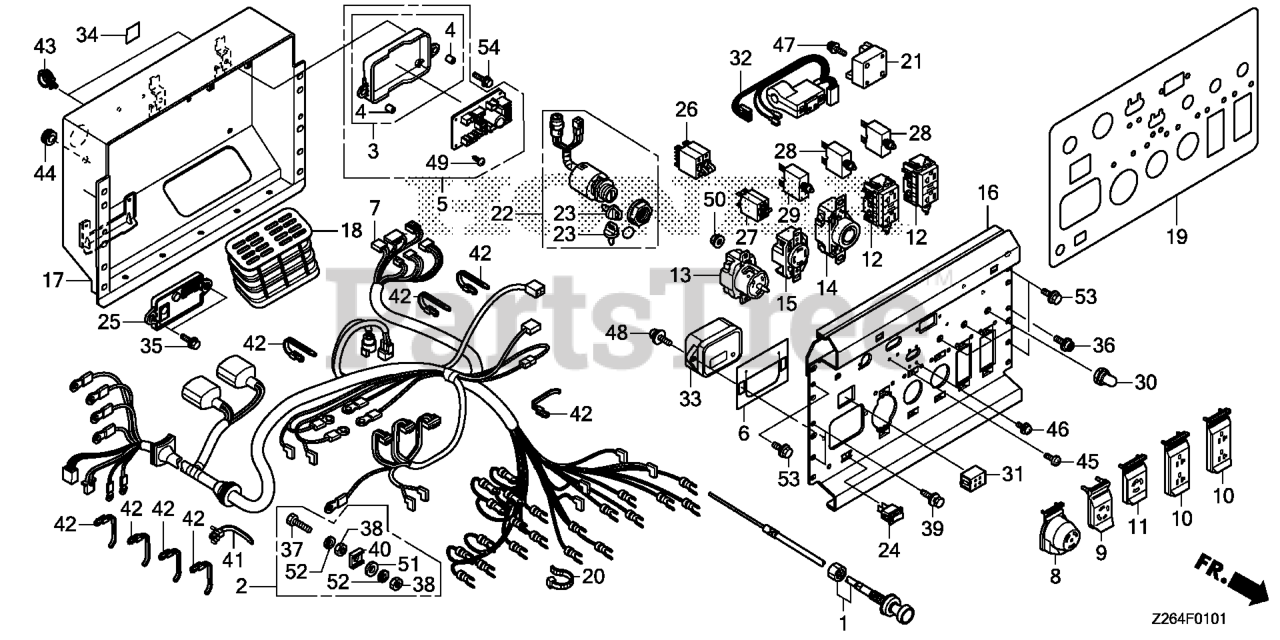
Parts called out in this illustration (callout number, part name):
1	CABLE, CHOKE
2	TERMINAL SET, GROUND
3	CASE, AUTOMATIC VOLTAGE REGULATOR
4	COLLAR, AUTOMATIC VOLTAGE REGULATOR CASE
5	CASE ASSY., AUTOMATIC VOLTAGE REGULATOR
6	SHEET, WATERPROOF
7	WIRE HARNESS ASSY., CONTROL (AG)
8	COVER, RECEPTACLE (50A-125/250V)
9	COVER, RECEPTACLE (30A-125/250V)
10	COVER, RECEPTACLE (20A-125V)
11	COVER, RECEPTACLE (30A-125V)
12	RECEPTACLE (20A-125V) (GFCI)
13	RECEPTACLE (50A/125-250V)
14	RECEPTACLE (30A-125V)
15	RECEPTACLE (30A-125/250V)
16	PANEL, CONTROL *NH105* (AG) (MAT BLACK)
17	COVER, CONTROL BOX *NH105* (MAT BLACK)
18	DUCT, CONTROL BOX
19	MARK, PANEL (AG)
20	TIE, CABLE (C)
21	CONTROL UNIT, IDLE
22	SWITCH ASSY., COMBINATION
23	KEY ASSY., COMBINATION SWITCH (W05)
24	SWITCH ASSY., IDLE CONTROL
25	SENSING UNIT (CO)
26	BREAKER, CIRCUIT (41A)
27	BREAKER, CIRCUIT (30A)
28	PROTECTOR, CIRCUIT (20A)
29	PROTECTOR, CIRCUIT (30A)
30	COVER, CIRCUIT PROTECTOR
31	LED ASSY., INDICATER
32	RELAY ASSY. (GFCI)
33	MONITOR ASSY., MULTI
34	MARK, FUSE
35	BOLT, FLANGE (5X14)
36	BOLT, FLANGE TORX (6X12)
37	BOLT, HEX. (6X28)
38	NUT, HEX. (6MM)
39	BOLT, GROUND (6X16) (WASHER 12.5MM) (ZN)
40	RETAINER (6MM)
41	CABLE, STRAP
42	TIE, CABLE
43	CLIP, WIRE HARNESS
44	GROMMET, CHOKE CABLE
45	SCREW, PAN (3X5) (NOT AVAILABLE)
46	SCREW-WASHER (3X6)
47	SCREW-WASHER (5X14)
48	SCREW-WASHER (6X16)
49	SCREW, TAPPING (4X10) (PO)
50	NUT, FLANGE (4MM)
51	WASHER, PLAIN (6MM)
52	WASHER, SPRING (6MM)
53	BOLT, FLANGE (6X12) Use up to Engine SN 1543277.
54	BOLT, FLANGE (6X16) Use from Engine SN 2056820.
